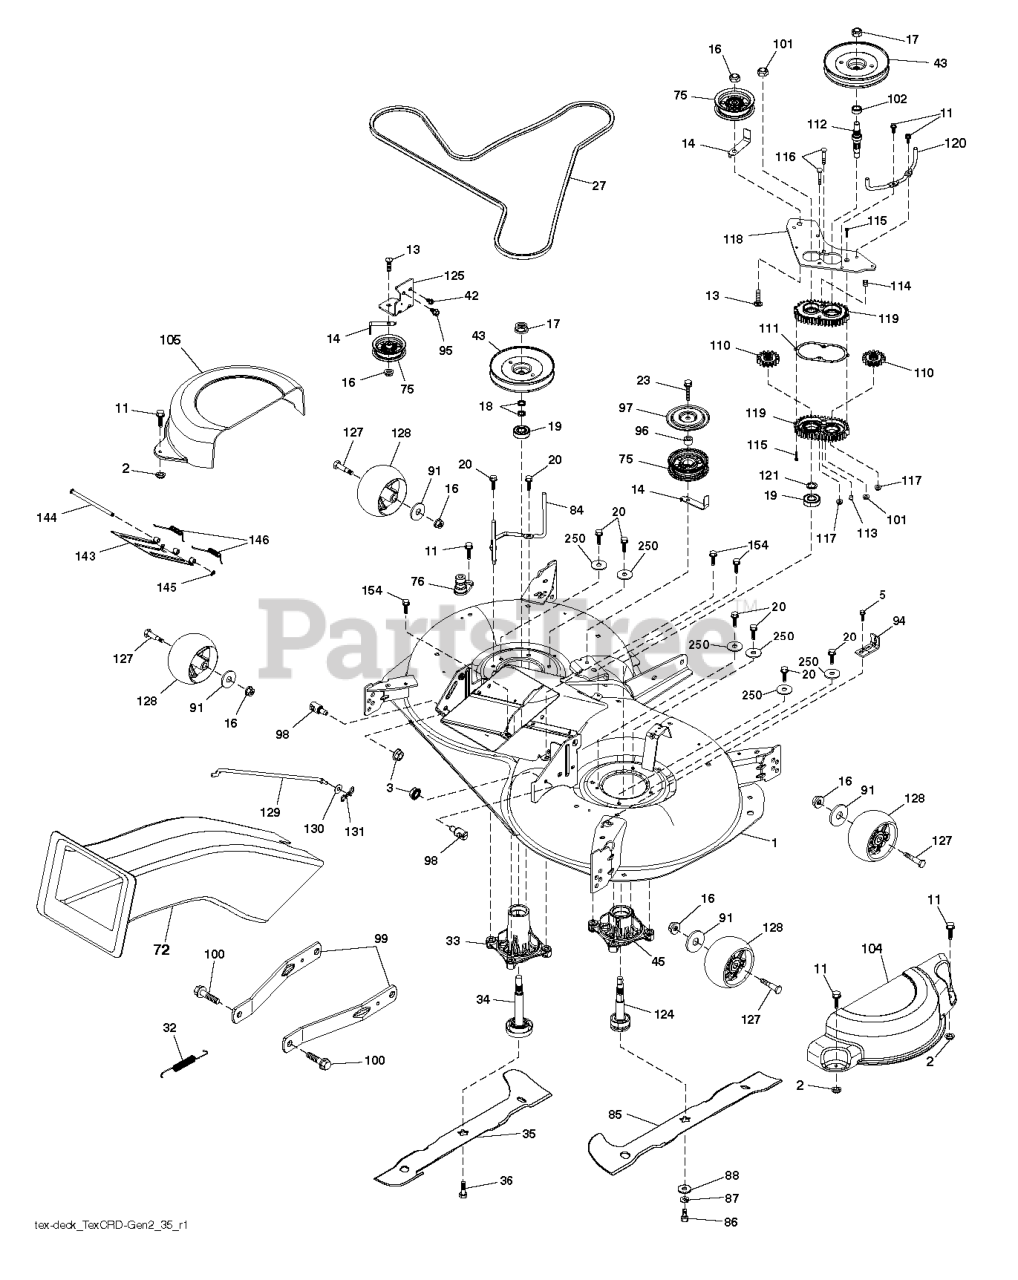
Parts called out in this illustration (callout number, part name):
1	DECK SVC 107HP.EZMUL.498
2	PALNUT 1/4
3	NUT LOCK HEX FLANGE 5/16-18
5	BOLT.5/16HEX.WHS.HD
11	SCREW.1/4-20X5/8
13	BOLT.3/8-16X1.50
14	KEEPER, BELT IDLER
16	NUT LOCK FLG 3/8-16 UNC
17	NUT.FLANGE.LOCK.TOP
18	WASHER.SPACER.MANDREL
20	SCREW, WASHER HEAD
23	SCREW LT
27	BELT BELT. ELECTRIC MOWER DRIV
32	SPRING 107CM & 97CM ELECTRIC D
33	RP.HOUSG.MAND.REV.TALL.N/GRS
34	RP.SAFT ASM.REV.TALL.N/GREASE
35	BLADE.107.LH.SINGLE.NON.QD
36	BOLT.WASHER.ASM.7/16-2
42	SCREW
43	PULLEY PULLEY MANDREL 5.438 PD
45	RP HOUSING.MANDREL.REV.REVS.
72	RP.CHUTE 107/97 TEX GENII
75	FLAT IDLER PULLEY
76	PORT.WASHOUT
84	KEEPER KEEPER. LH MANDREL BELT
85	BLADE.107.RH.SINGLE.NON.QD
86	BOLT.3/8-24X1.25GR8. LHTHRD
87	LOCKWASHER
88	WASHER.BLADE
91	WASHER
94	BRKT.CLUTCH.CABLE
95	SCREW, 3/8-16X3/4
96	SPACER
97	PROTECTOR
98	STUD.FASTNER.W/ANTI-ROTATE
99	ARM.SUSPENSION.MOWER.R
100	BOLT.SHOULDER
101	NUT.CROWNLOCK.9/16 -18.UNC
102	SPACER BEARING
104	COVER.MANDREL.107.RH.GEN.2
105	COVER.MANDREL.107.LH.GEN.2
110	CRD.SPUR.GEAR
111	GASKET GASKET GEARCASE
112	SHAFT SHAFT. CRD GEARCASE ADAP
113	PLUG PLUG OIL
114	VALVE VALVE RELIEF
115	SCREW
116	BOLT.CARIGE.SS.1/4-20X1.75GR5
117	NUT T
118	ARM ARM. CLUTCHING 107 TEX CRD
119	GEARCASE GEARCASE SUBASM
120	KEEPER KEEPER. RH MANDREL BELT
121	WASHER WASHER
124	SUB.ASM.REVERSE.THREAD.REV
125	BRACKET
127	BOLT.SHOULDER.3/8-16X3-5/8.
128	RP WHEEL. GUAGE RALLY
129	ROD ROD. SWAY CRD GEN II
130	WASHER
131	PIN.COTTER.5/16.BOW TI
143	COVER DOOR.107 CM CRD EZ MULCH
144	PIN PIN.HINGE
145	E-RING.5/16"
146	SPRING SPRING: EZ MULCH DOOR
154	SCREW T-30 1/4-20 X
